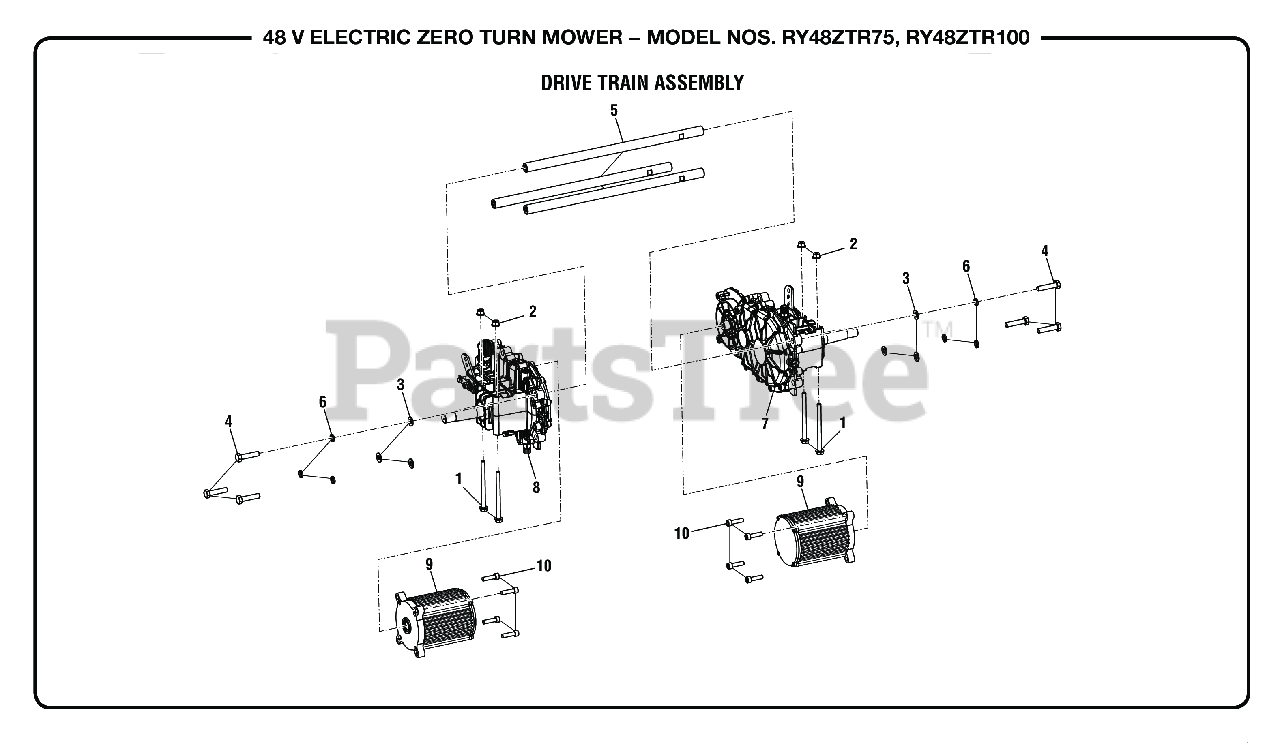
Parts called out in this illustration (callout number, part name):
1	Flange Bolt (M8 x 110 mm, Hex Hd.)
2	Flange Nut (M8) (For Drive Motor Controller V)
3	Washer (OD20 x ID10.5 x 2t)
4	Bolt (M10 x 45 mm, Hex Hd.)
6	Lock Washer (M10)
7	Gearbox, Left
8	Gearbox, Right
9	Drive Motor, ZTR
10	Screw (M8 x 30 mm, Soc Hd.)
